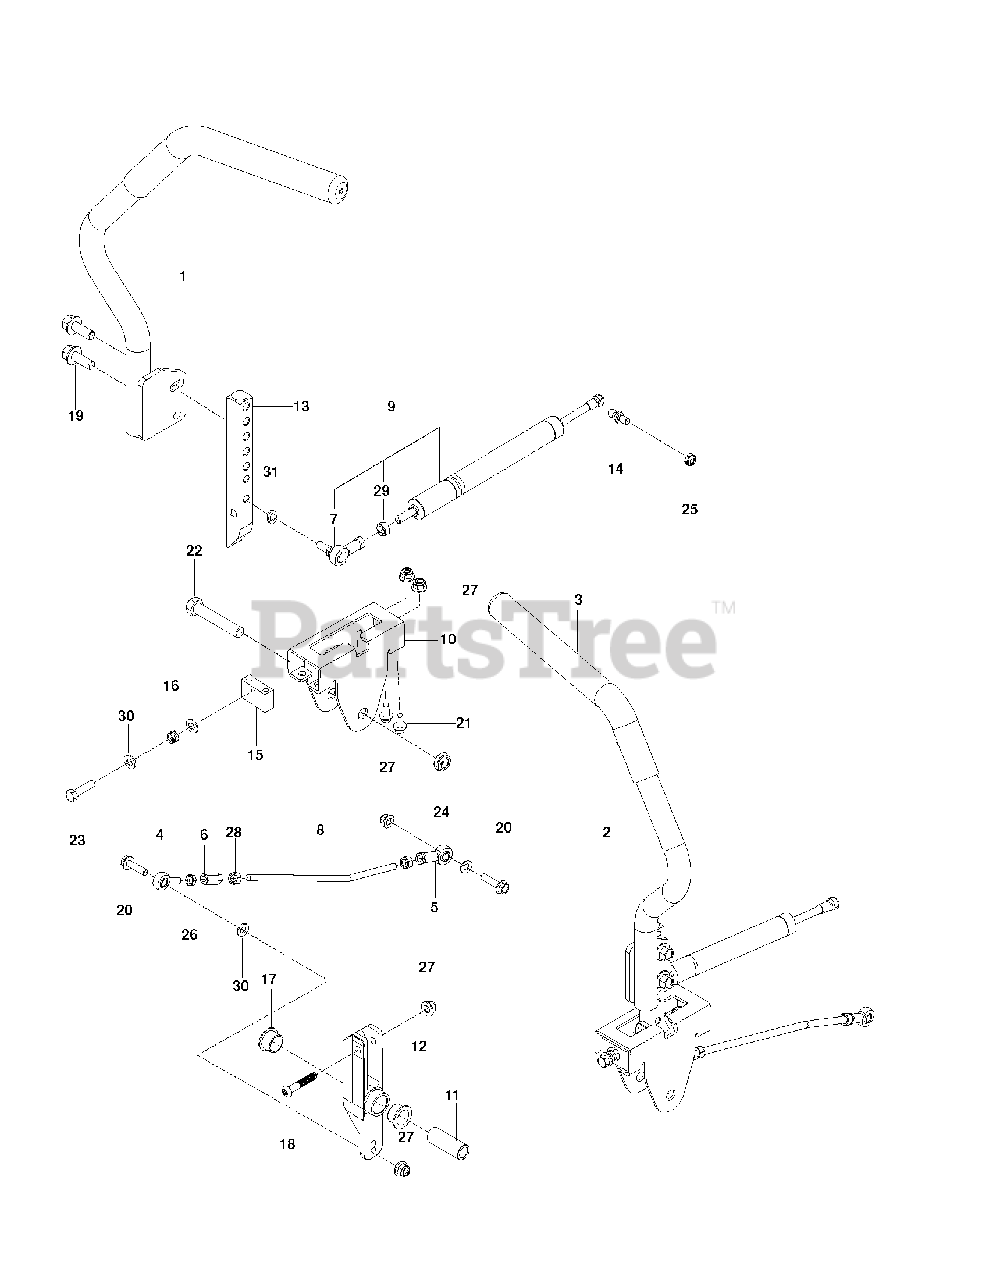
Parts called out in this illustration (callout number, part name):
3	GRIP - DRIVE LEVER
4	ROD END LH
5	RH ROD END
6	ROD END COUPLER
7	ROD END
8	ROD, CONTROL
9	ASSEMBLY, DAMPENER
10	BRACKET, CONTROL
11	SPACER, PIVOT CONTROL
13	LEVER, MOTION
14	10MM BALL STUD
15	BLOCK, TRACKING
17	BEARING, FLANGE
19	HHFS 3/8-16 X 1 GRD 5 ZD
20	HHFS 5/16-18 X 1.25 TPBLT GD 5
21	HHFS 5/16-18 X 3/4
22	HCS 1/2C X 2 3/4
23	HCS 5/16-18X1-3/4 TPBLT
24	NUT 1/2-13 HEX JM NYL
25	5/16-18 THIN PROF NY
26	NUT 5/16F LEFTHAND
27	5/16-18 NYLOC FLANGE NUT
28	NUT 5/16F
29	NUT M8 X 1.25 STD HEX
30	FLAT WASHER 5/16 SAE
31	WASHER 5/16 LOCK
